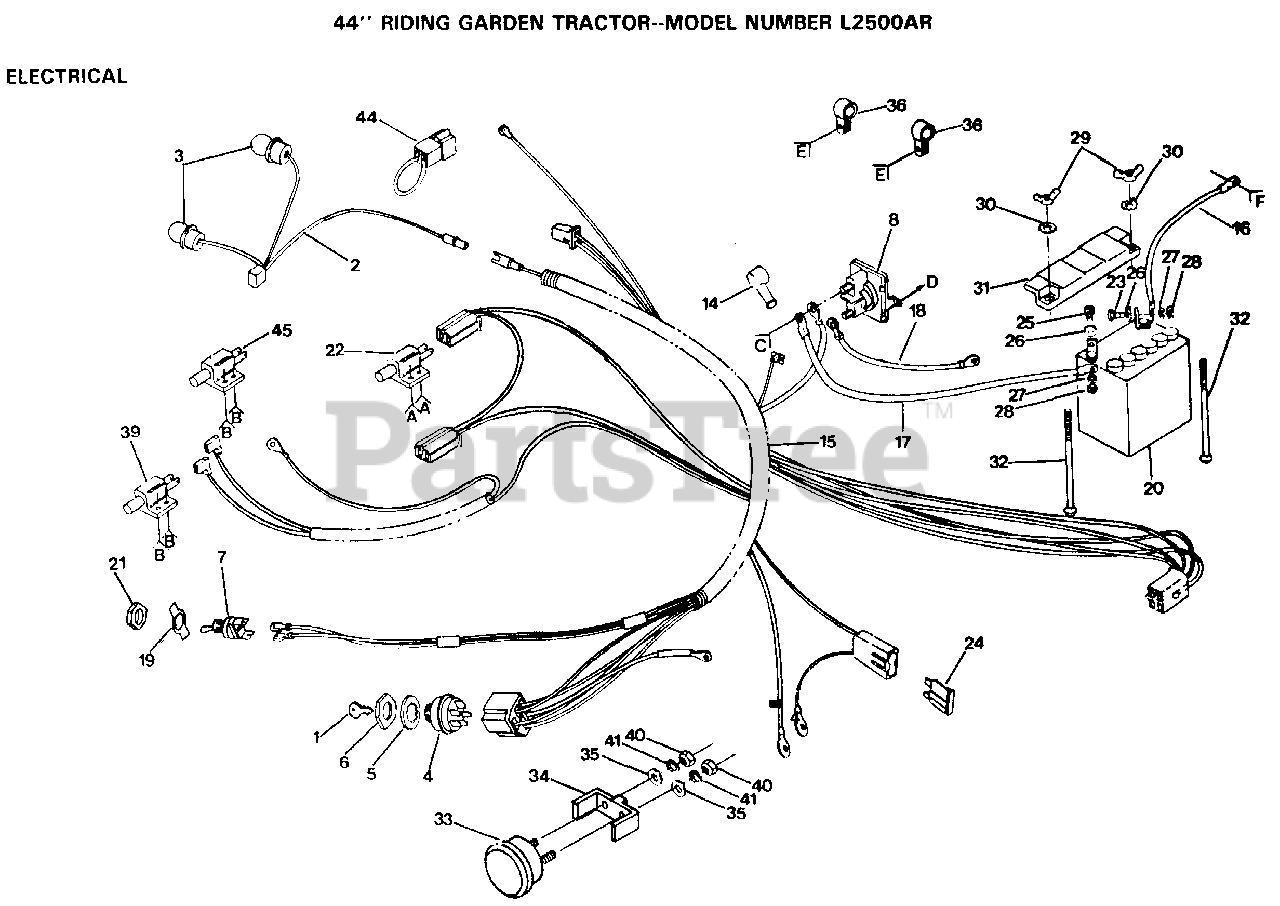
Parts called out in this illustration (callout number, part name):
2	HARNESS T
5	LOCKWASHER
6	CONDUIT NUT L
7	LIGHT SWITCH T
16	"CABLE T, BATTERY"
17	CABLE LT
18	CABLE T
19	SWITCH PLATE LT
22	SWITCH-INTER. GT
23	SCREW
24	FUSE HYT
25	BOLT LT
26	WASHER
27	LOCKWASHER
30	LOCKWASHER GT
32	BOLT
33	AMMETER T
35	WASHER
36	CLIPT
39	SWITCH INTERLOCKT
45	SWITCH T
